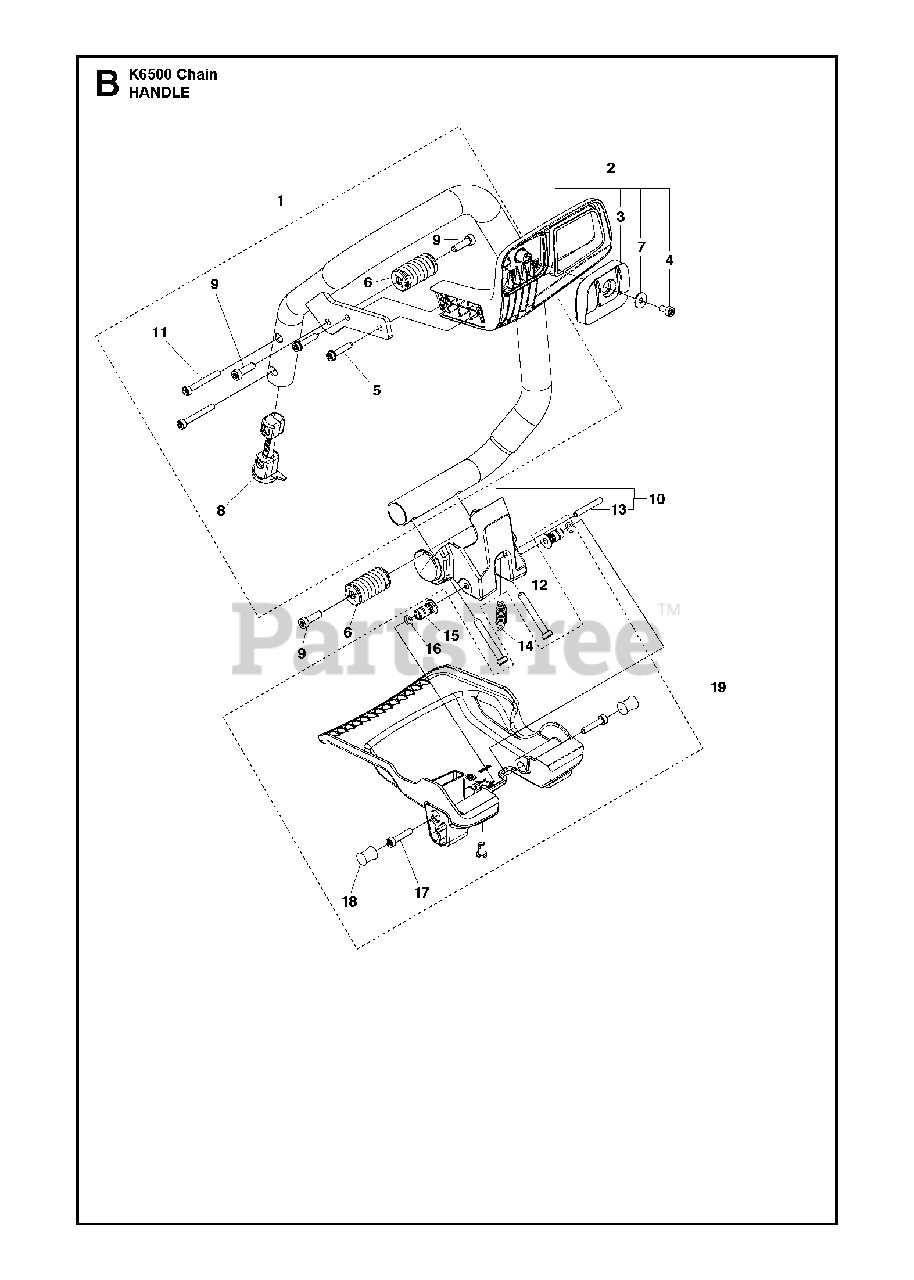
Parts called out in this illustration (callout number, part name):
4	SCREW ITXSCT
5	SCREW ITXSCT
6	ANTIVIBRATION ELEMENT
9	SCREW ITXSCM
12	SCREW ITXSCT
17	SCREW ITXSCM
